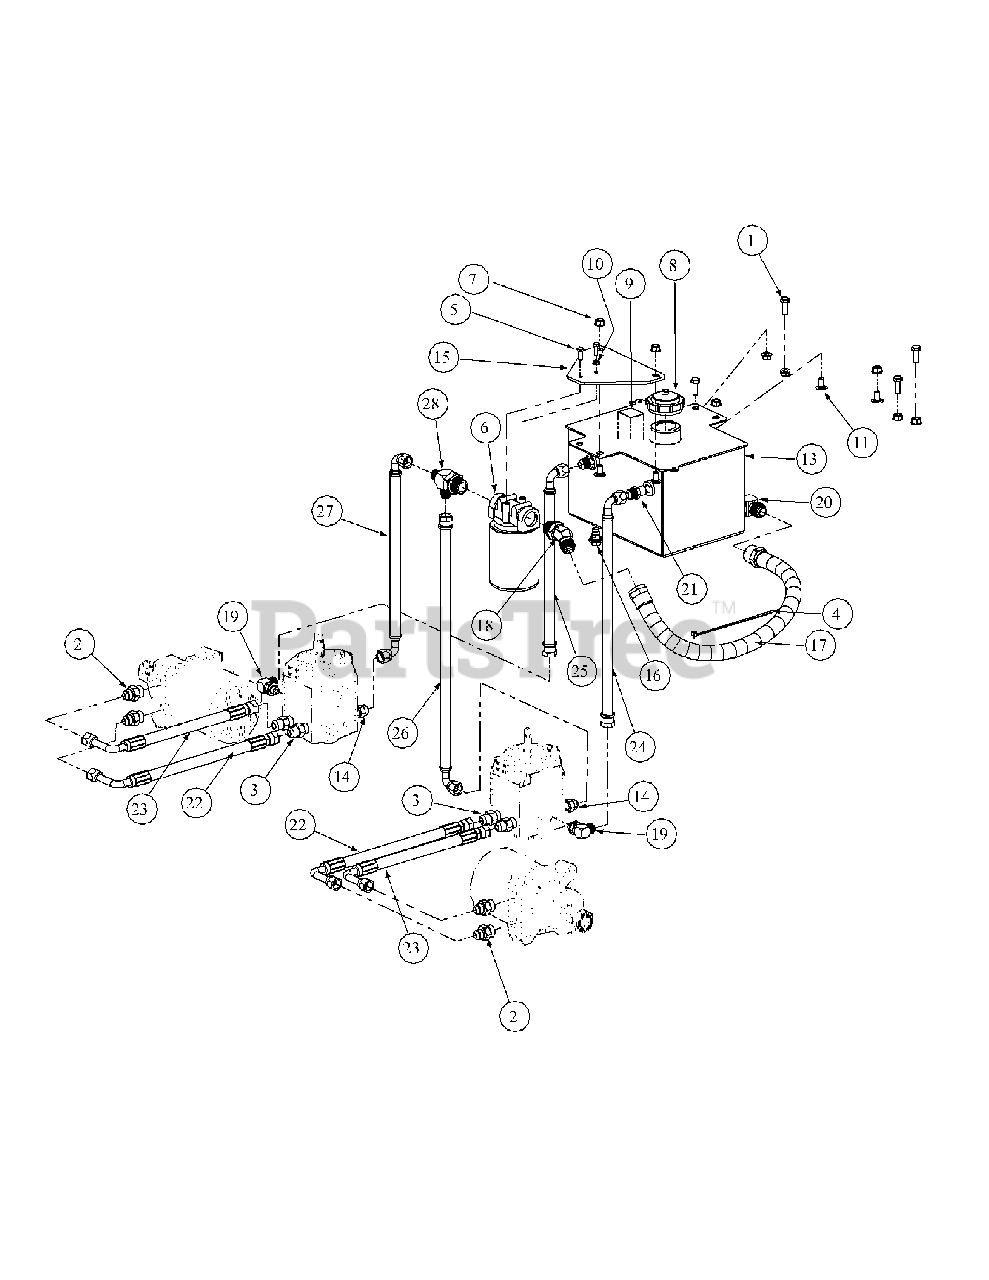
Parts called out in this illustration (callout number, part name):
1	Hex Cap Screw, 3/8-16, 1
2	Fitting 1/2 x 3/4 - O Ring
3	Fitting 1/2 x 3/4 - O Ring to Flare
4	Cable Tie, 3/16 x .05 x 7.4
5	Hex Cap Screw, 1/4-20, .75
6	Filter Head 3/4
7	Hex Nut Flange Lock, 3/8-16
8	Cap, Hydro Oil Tank
9	Decal Oil Only 20W50
10	Lock Washer, 1/4
11	Carriage Bolt, 3/8-16 x .75 LG.
13	Hydraulic Tank Assembly
14	Fitting Connector, 1/2 x 3/8
15	Oil Filter Mounting Plate
16	Oil Pan Drain w/ Seal and Plug
17	Tank to Filter Hose Assembly
18	Connector, 3/4 x3/4
19	Elbow Fitting, 3/8 O-ring, 1/2 Flare
20	Fitting Elbow, 1/2 x 1/2
21	Fitting, 3/8 NPT, 1/2 Flare
22	Long Pressure Hose Assembly
23	Short Pressure Hose Assembly
24	17.75" Return Hose Assembly, RH
25	14" Return Hose Assembly, LH
26	21.25" Supply Hose Assembly, RH
27	15.50" Supply Hose Assembly, LH
28	Tee Fitting, 3/4 x 1/2 x 1/2
